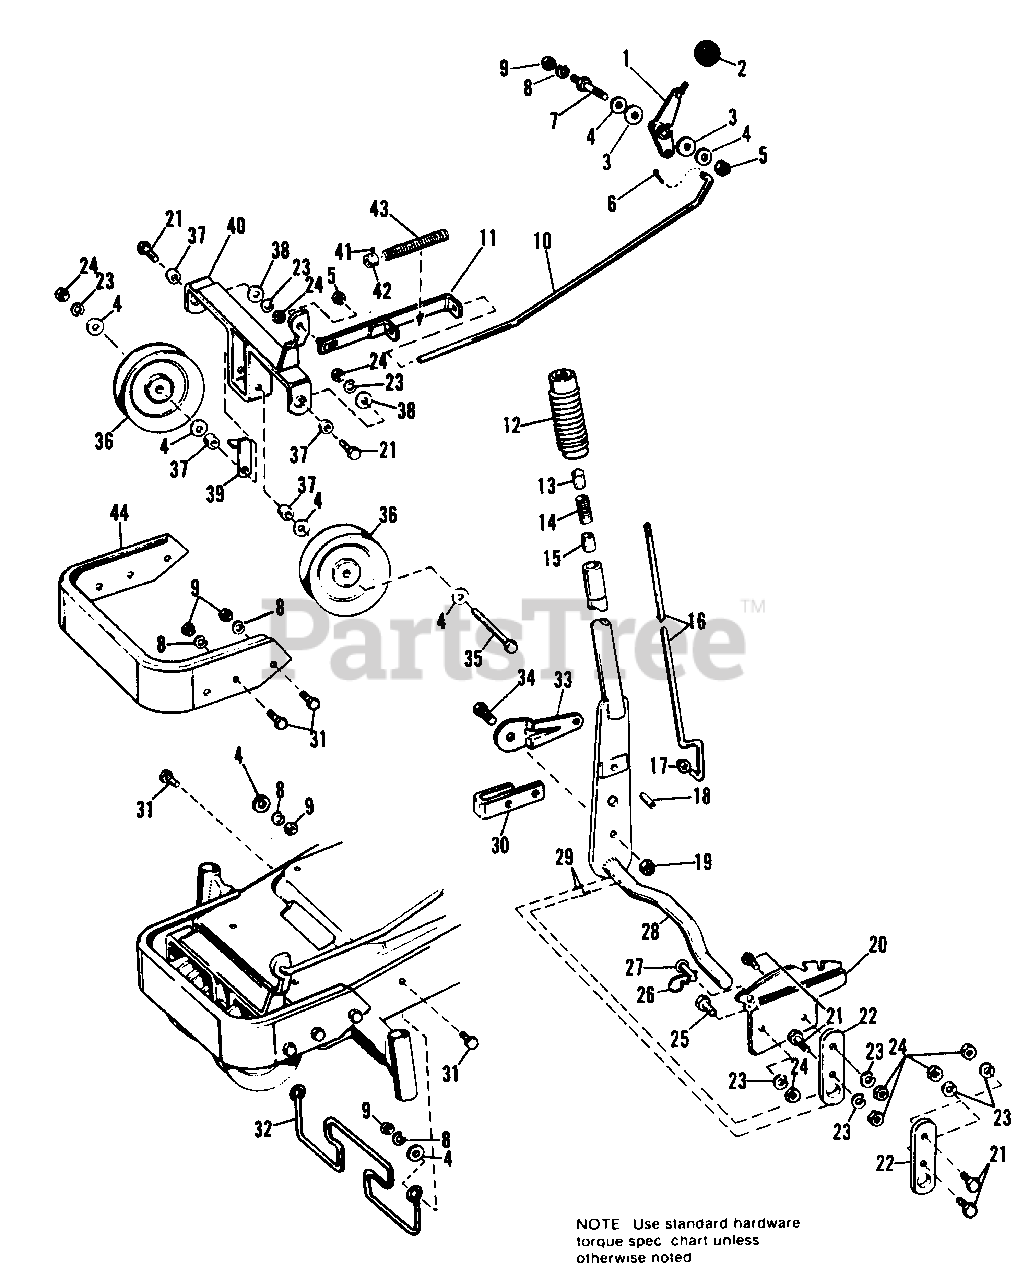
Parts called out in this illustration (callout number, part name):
1	LEVER ASSY.
3	WASHER, Special
4	WASHER, Plain, 5/16
5	LOCKNUT, Hex, 5/16-18
6	PIN, Cotter, 3/32 x 5/8
8	LOCKWASHER, 5/16
9	NUT, Hex, Full, 5/16-18
10	ROD, Clutch
11	GUIDE ASSY., Rod
12	GRIP, Handle
13	BUTTON, Thumb
16	ROD, Lift Lever
18	PIN, Roll, 3/8 x 1
19	LOCKNUT, Hex, 3/8-16
20	QUADRANT, Lift Lever
21	CAPSCREW, Hex Hd., 3/8-16 x 1
22	BAR, Bearing
23	LOCKWASHER, 3/8
24	NUT, Hex, Full, 3/8-16
25	CAPSCREW, Hex Hd., 3/8-16 x 3/4
26	CLIP, Spring
28	LEVER ASSY., Lift
29	PIN, Roll, 3/16 x 1
30	LATCH, Lift Lever
31	CAPSCREW, Hex Hd., 5/16-18 x 3/4
32	STOP, Belt, P.T.O.
33	LEVER, Lift
34	CAPSCREW, Hex Hd., 3/8-16 x 7/8
35	CAPSCREW, Hex Hd., 3/8-16 x 4-1/4
36	PULLEY, Idler
38	WASHER, Plain, 3/8
39	STOP ASSY. (990780 Only)
40	CLEVIS ASSY., Pulley
41	SETSCREW, 1/4-20 x 3/8
42	COLLAR, Set
44	BUMPER, Front
